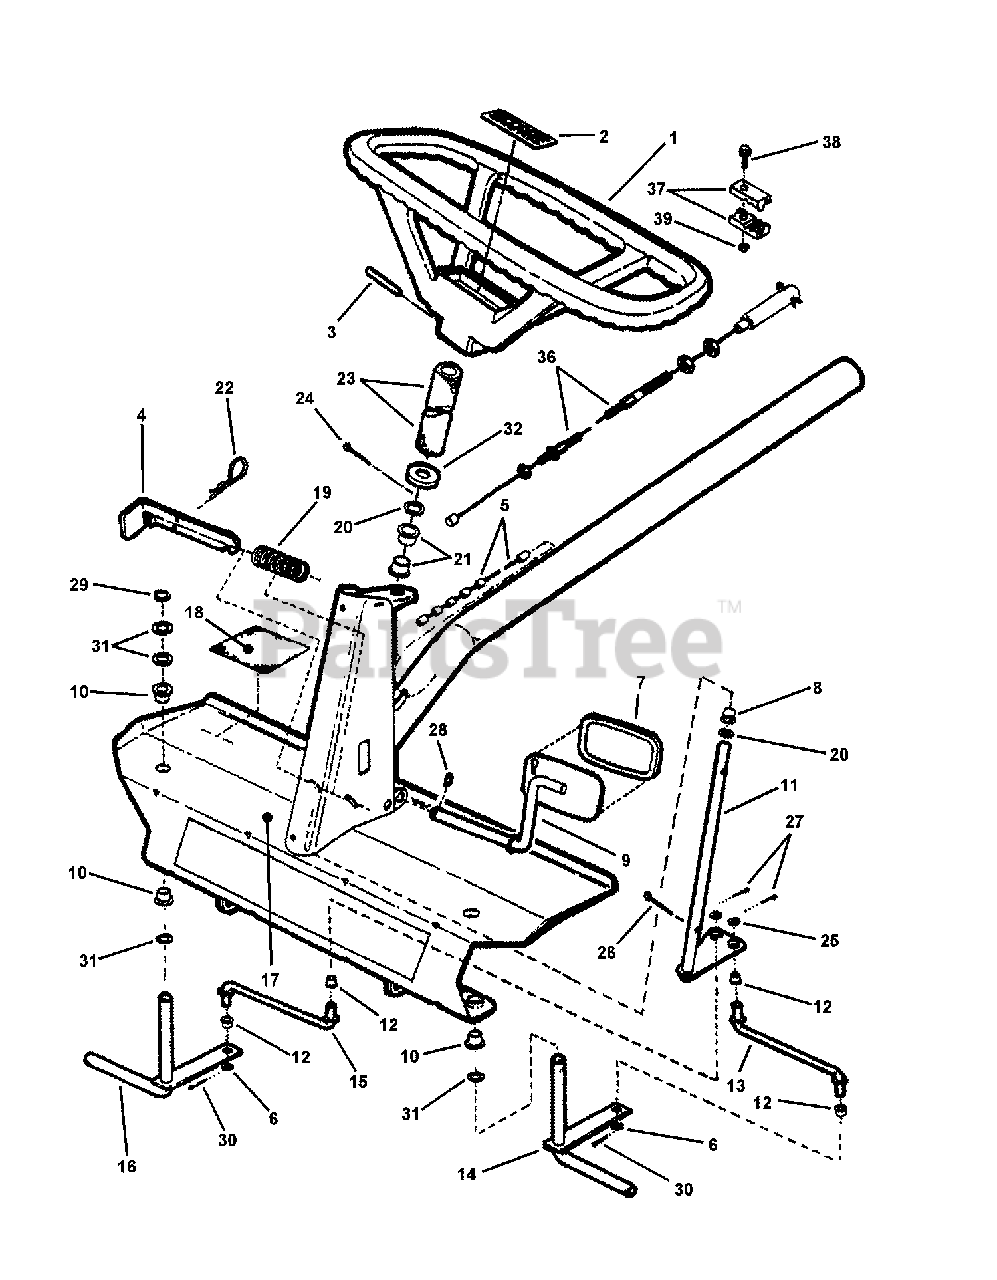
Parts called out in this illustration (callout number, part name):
1	ASSEMBLY, Steering Wheel (for 5/8" shaft)
2	LOGO, Steering Wheel
3	PIN, 1/4 x 1-1/2" Roll
4	LATCH, Parking Brake
5	CABLE, Clutch/Brake (55" long)
6	WASHER, 3/8" Flat SAE
7	PAD, Clutch/Brake Pedal
8	BUSHING, Nylon
9	WELDMENT, Clutch/Brake Pedal
10	BEARING, Nylon
11	WELDMENT, Steering Shaft
12	BUSHING, Tie Rod
13	TIE ROD, Left Hand (9.91" long)
14	KING PIN Weldment, Left Hand
15	TIE ROD, Right Hand (9.91" long)
16	KING PIN Weldment, Right Hand
17	WELDMENT, Front Axle, Wide
18	FOOT PAD, Long
19	SPRING, Parking Brake Latch
20	WASHER, .66 x 1.31 x .09 Flat
21	BUSHING, Nylon
22	HAIR PIN 2-1/4"
23	FOAM COVER, Steering Shaft
24	PIN, 3/16 x 1" Cotter
25	WASHER, 3/8" Flat
26	PIN, 3/16 x 1-1/2" Cotter
27	PIN, 5/32 x 1" Cotter
28	RING, 1/2" External Retaining (Heavy Duty)
29	RING, 3/4" External Retaining
30	PIN, 1/8 x 3/4" Cotter
31	WASHER, .77 x 1.13 x .06 Flat
32	COVER, Steering Shaft
36	CABLE, Brake (29" long)
37	CONNECTOR, Cable
38	SCREW, 1/4-20 x 3/4" Hex Head Cap, GR5
39	NUT, 1/4-20 Hex Center Lock, GR5 or B
